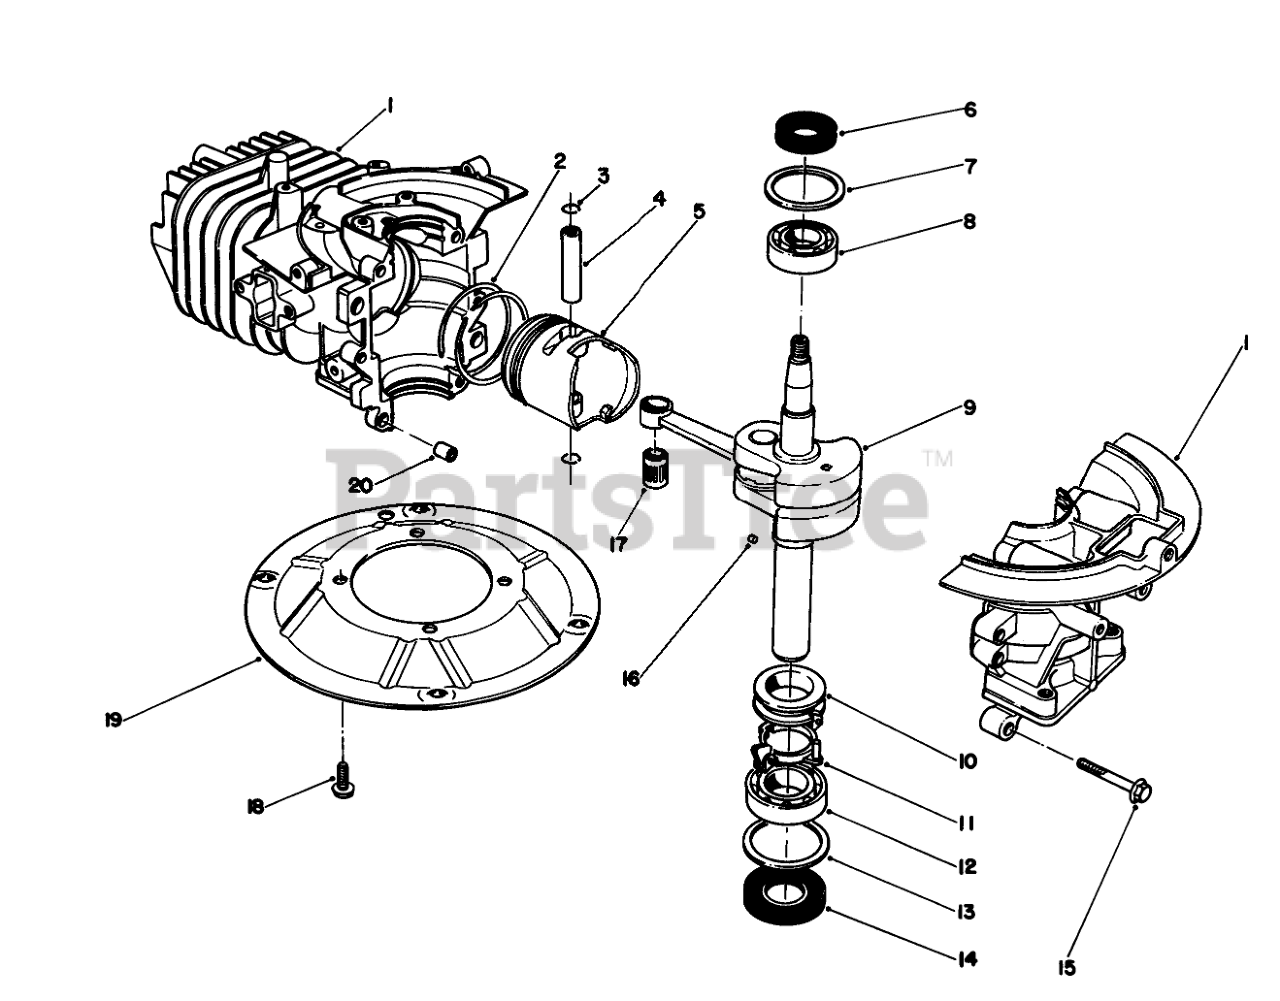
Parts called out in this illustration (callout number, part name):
1	CRANKCASE
2	RING SET
4	PIN-PISTON
5	Piston
6	OIL SEAL
7	WASHER-UPPER
8	BEARING-UPPER
9	Pin-Wrist
10	SPACER
11	BRACKET
12	LOWER BRG
13	WASHER-LOWER
14	SEAL-OIL
17	BEARING
19	PLATE-MOUNTING
